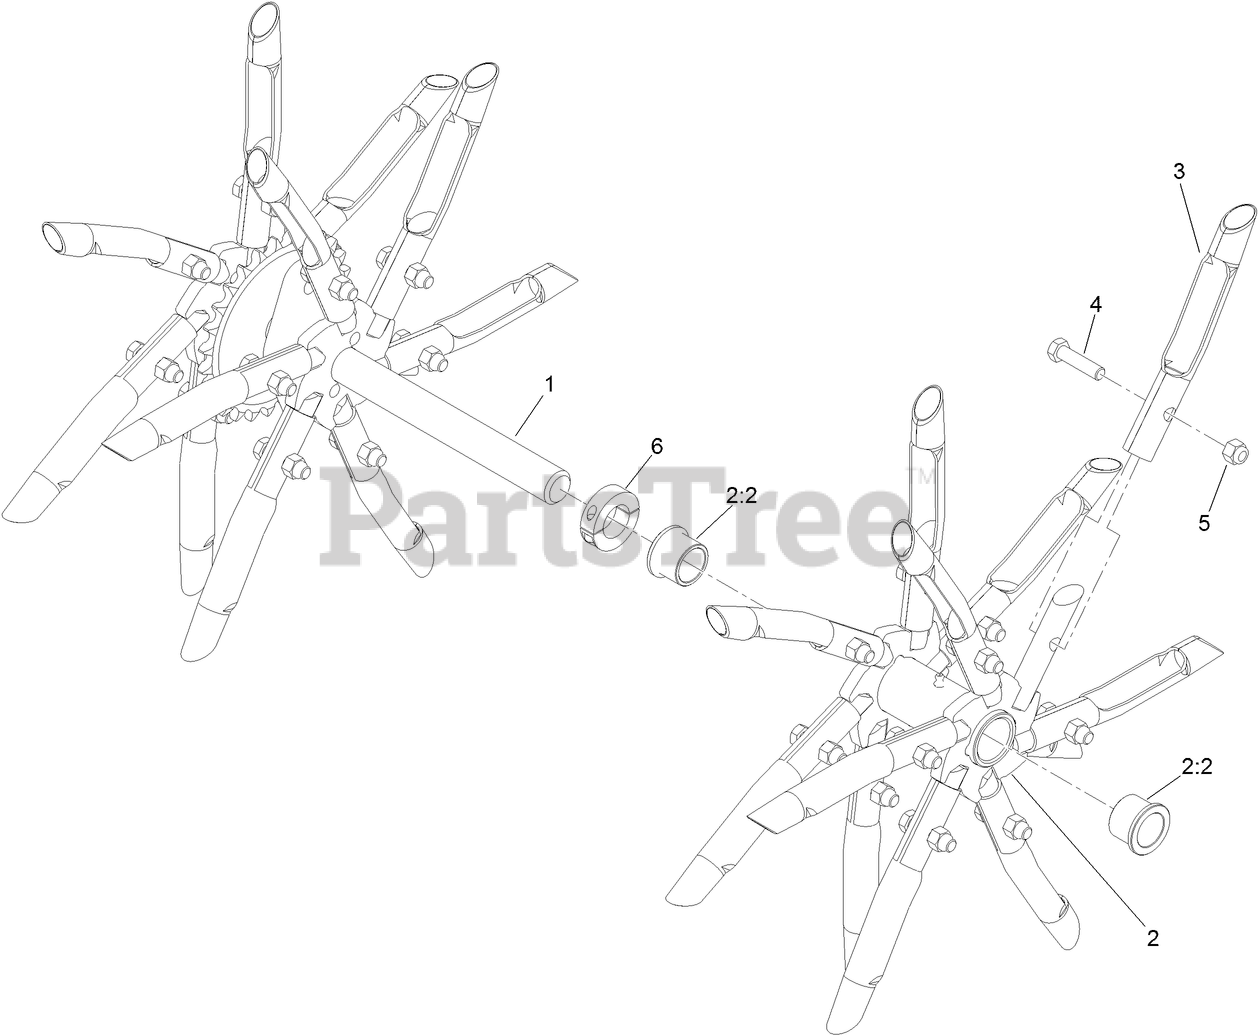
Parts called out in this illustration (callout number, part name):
1	TINE SHAFT-RH
2	TINE SHAFT FLOAT ASM
2:2	BUSHING-FLANGE
3	TINE-CORING (3/4 INCH)
4	SCREW-HH
5	NUT-LOCK, NI
6	COLLAR-LOCKING
